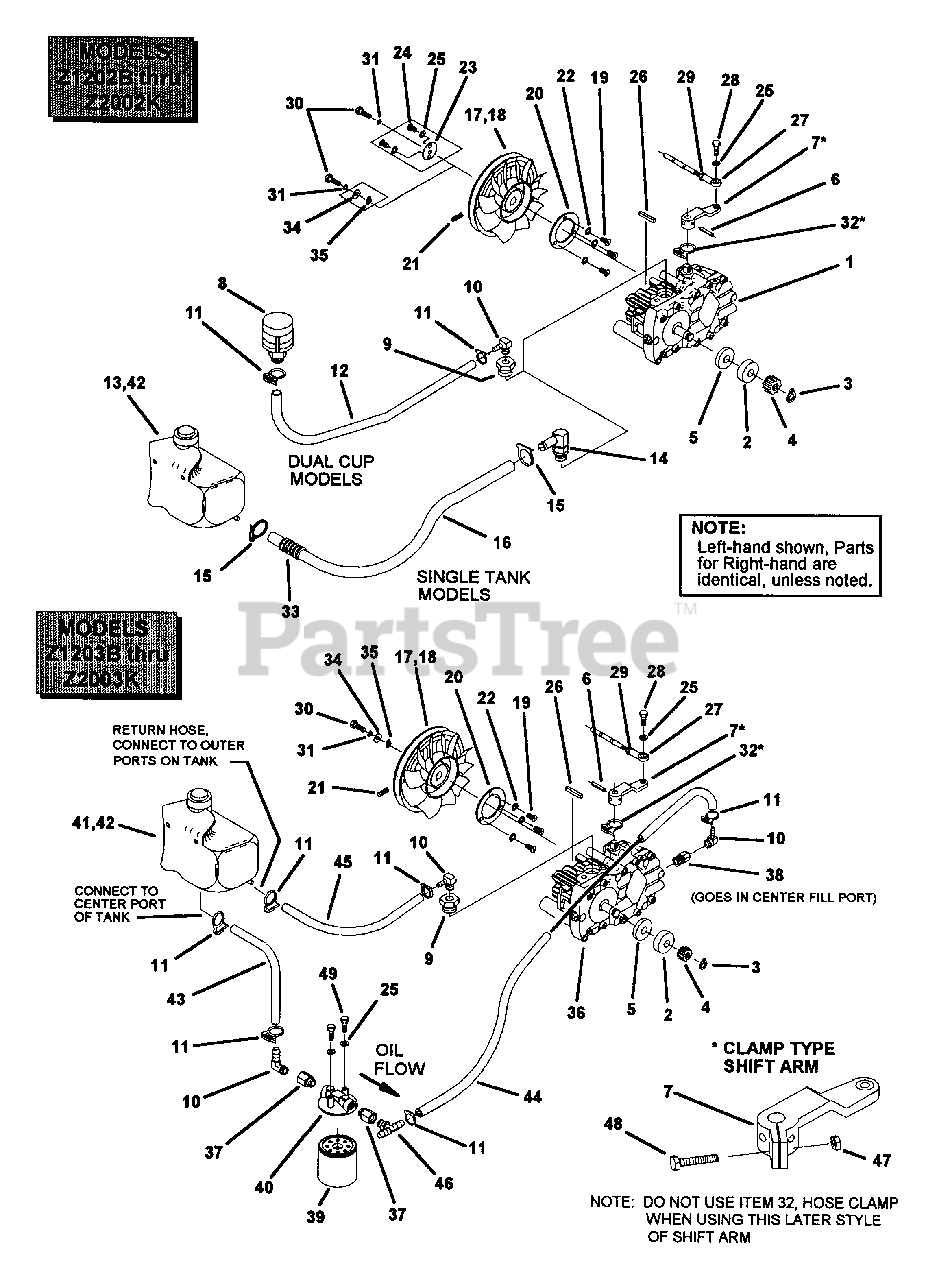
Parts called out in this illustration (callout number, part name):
1	HYDROSTAT TRANSMISSION, L.H.
1	HYDROSTAT TRANSMISSION, R.H.
2	BEARING, BALL
3	SNAP RING, EXT.
4	GEAR, 11 TOOTH
5	SPACER, BEARING
6	ROLL PIN, 5MM X 26MM
7	SHIFT ARM
8	RESERVOIR CUP, w/ cap
9	ADAPTER, 7/8-14M TO 1/4-18F
10	HOSE BARB, 90D ELBOW, 1/4 NPTM X 3/8"
11	HOSE CLAMP, 19/32-21/32, NYLON
12	HOSE, OIL
13	TANK, 1.5 qt.
14	FITTING, 90, 7/8 SAE-5/8 HOSE
15	HOSE CLAMP, NYLON, 7/8-1"
16	HOSE, OIL 5/8" I.D.
17	PULLEY/FAN ASSEMBLY
18	FAN, 7" PLASTIC; 10 BLADE CCW
19	BOLT, 1/4-20 X 1/2", GR.5
20	WASHER, 3" O.D.
21	SETSCREW, SKHD 1/4-20 X 3/4" W/NYLOC
22	LOCKWASHER, 1/4" SPLIT SPRING
23	WASHER
24	SCREW, 1/4-20 X 1/2" PAN HD.
25	LOCKWASHER, 1/4" SPLIT SPRING
26	KEY, 5 MM SQ. X 25 MM
27	BALL JOINT, FEMALE 1/4-28
28	BOLT, 1/4-20 X3/4" GR. 5
29	NUT, 1/4-28
30	BOLT, 6 MM X 16 MM
31	LOCKWASHER, 6MM
32	HOSE CLAMP, NYLON 1"
33	COMPRESSION SPRING
35	SNAP-RING INT. 15 MM
36	HYDROSTAT TRANSMISSION, L.H.
36	HYDROSTAT TRANSMISSION, R.H.
37	ADAPTER, 9/16" SAE to 1/4 NPT
38	ADAPTER, 7/16" SAE TO 1/4 NPT
39	OIL FILTER
40	FILTER BASE
41	TANK, 1.5 QT, CHARGE PUMP STYLE
42	CAP, Oil Tank
43	HOSE, 6"
44	HOSE, 46", L.H.
44	HOSE, 24", R.H.
45	HOSE, 18"
46	TEE FITTING, 3/8 x 3/8 x 3/8 NPT
47	NUT, 1/4-20, NYLOC
48	BOLT, 1/4-20 X 1", GR.5
49	BOLT, 1/4-20 X 5/8", GR.5
